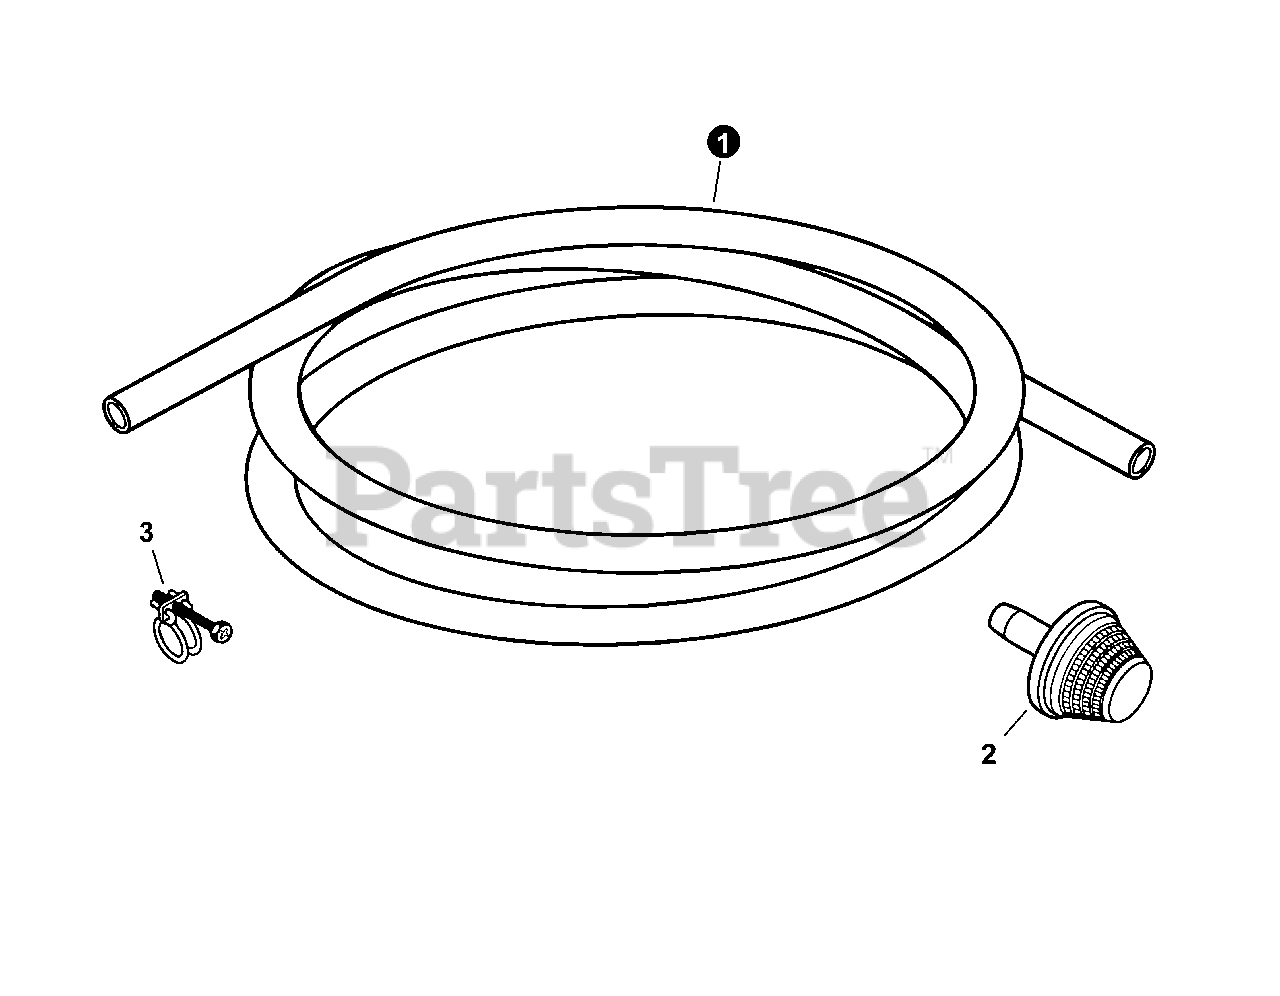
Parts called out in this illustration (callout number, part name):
1	HOSE, SUCTION - 1"×10'
2	STRAINER, DEBRIS
3	CLAMP, HOSE
